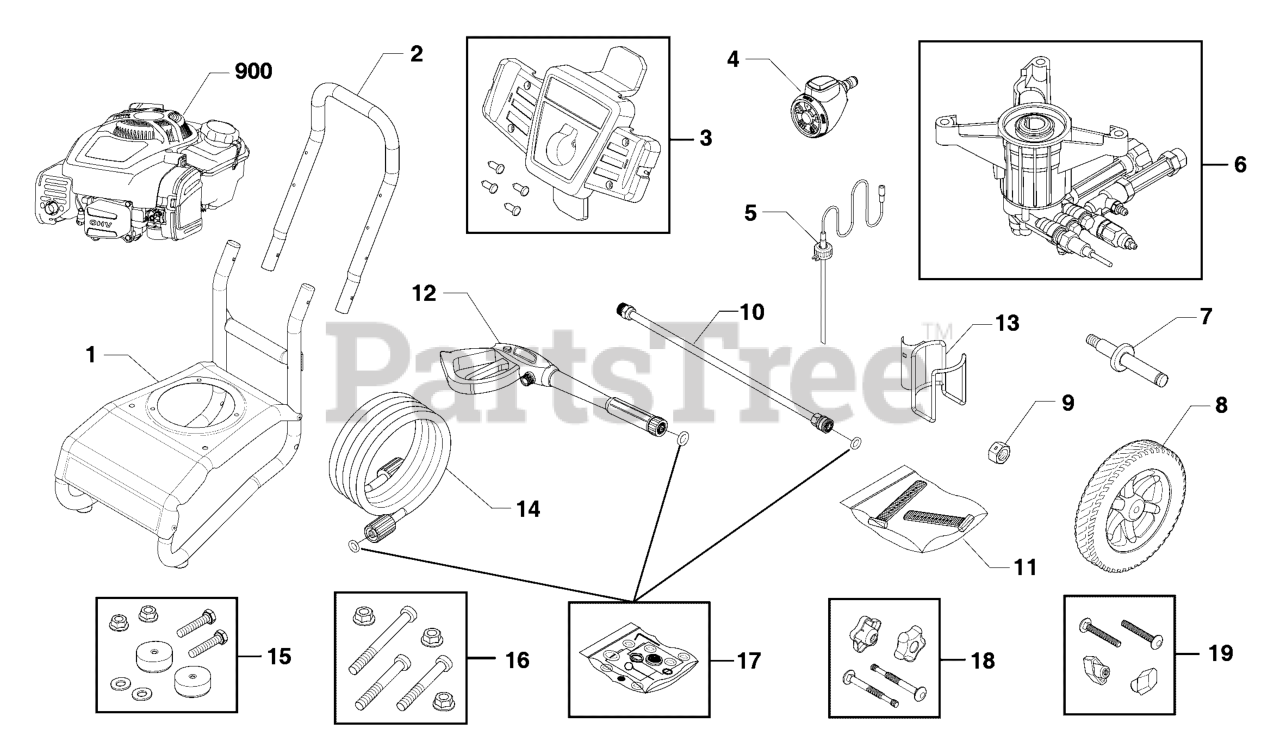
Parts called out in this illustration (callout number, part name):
12	GUN
14	HOSE
15	MOUNT-VIBRATION
16	KIT-HARDWARE PUMP MOUNTING
900	* ENGINE
